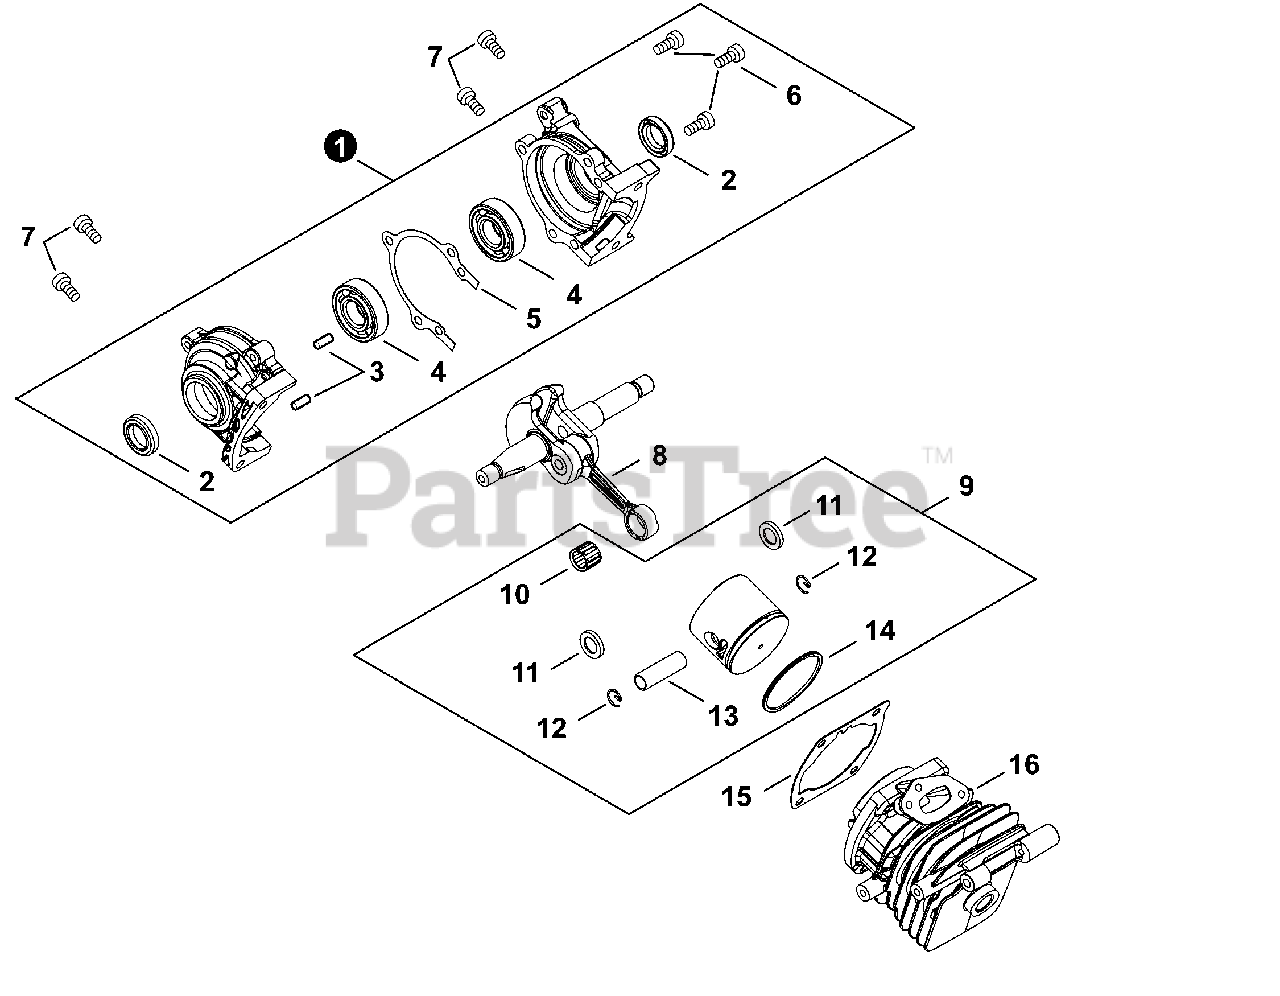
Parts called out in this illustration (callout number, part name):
1	CRANKCASE SET
2	SEAL, OIL 12
3	PIN, LOCATING 4×8
4	BEARING, BALL 6001
5	GASKET, CRANKCASE
6	BOLT, TORX 4×16
7	BOLT, TORX 4×16
8	CRANKSHAFT
9	PISTON KIT
10	BEARING, NEEDLE 8
11	WASHER, THRUST
12	RING, SNAP
13	PIN, PISTON 8
14	RING, PISTON
15	GASKET, CYLINDER
16	CYLINDER
